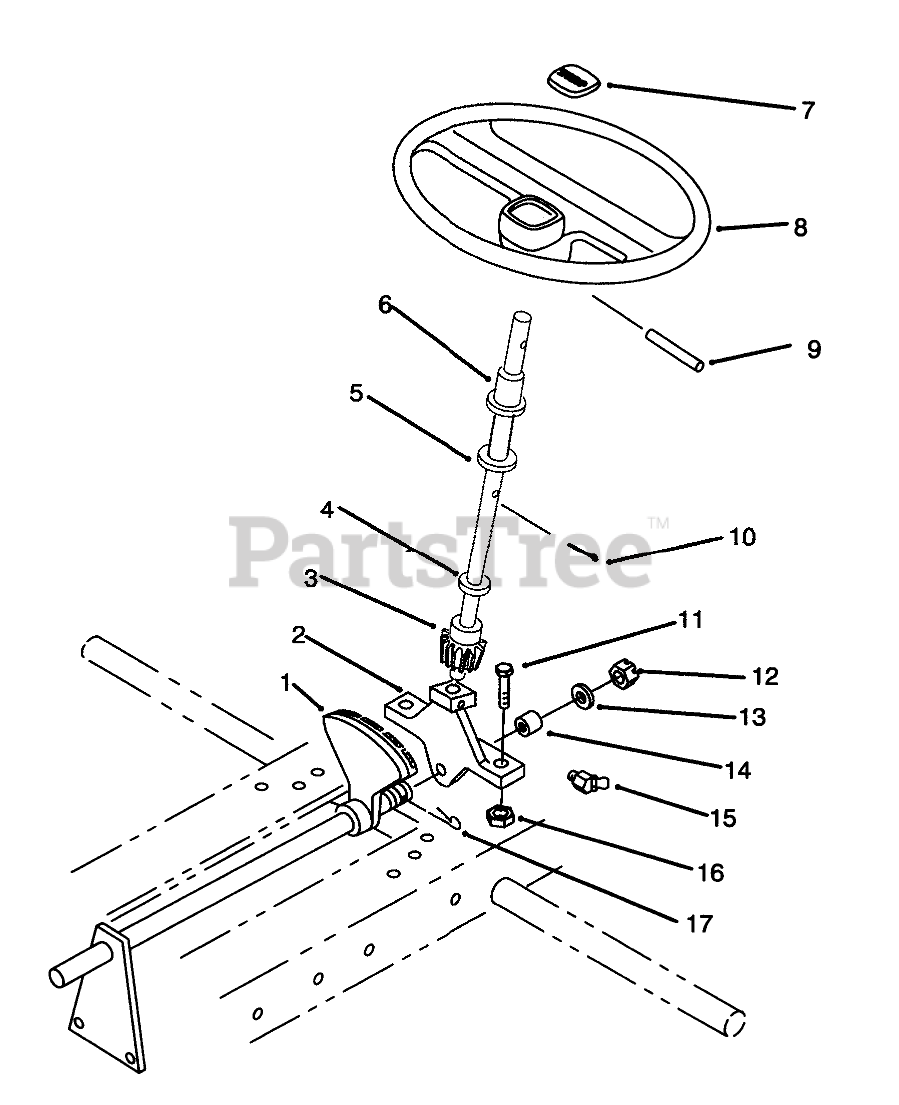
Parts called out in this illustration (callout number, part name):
1	Shaft
2	Support-Steering
3	STEERING SHAFT WA
4	O-RING
5	WASHER-SHIM
6	BEARING-FLANGED
7	STRG-WHL INSERT TORO
8	Wheel-Steering (Incl. Ref. #7)
9	PIN-ROLL
10	PIN-COTTER
11	SCREW-HH
12	NUT-HEX, SLOTTED
13	WASHER
14	BEARING-BRONZE
15	FITTING-GREASE
16	NUT-LOCK, NI
17	PIN-COTTER
